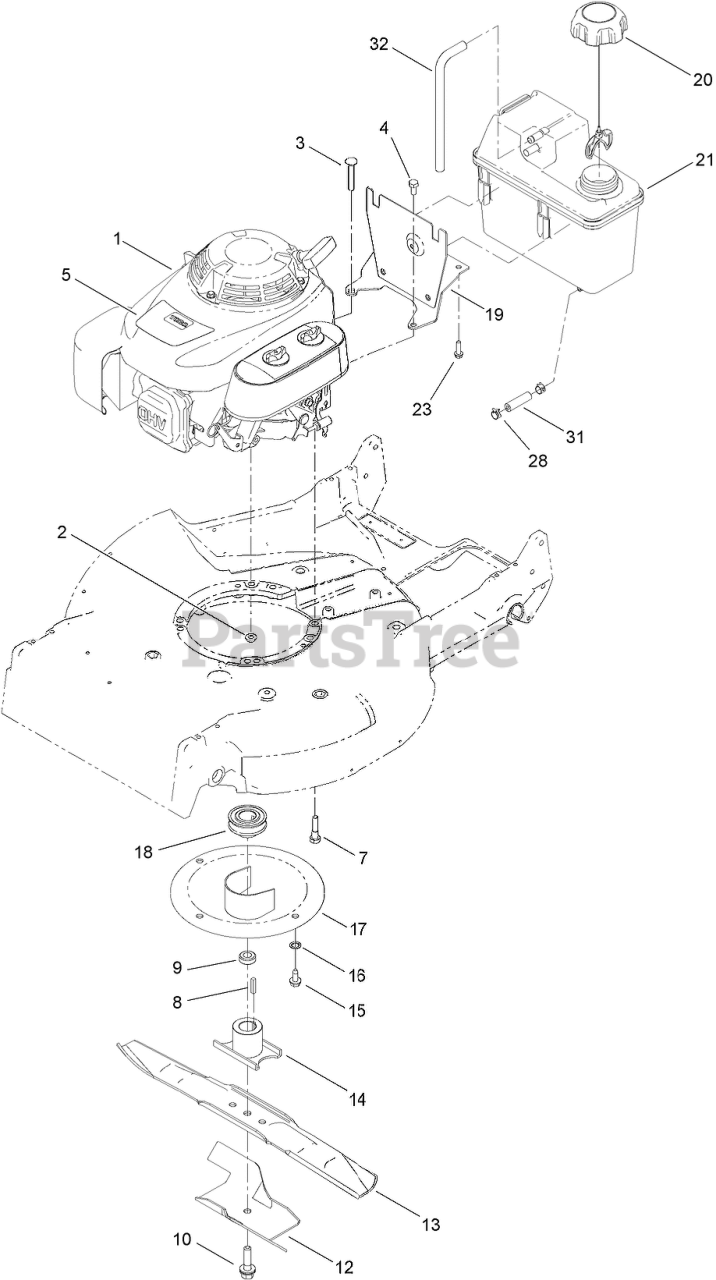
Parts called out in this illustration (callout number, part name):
2	NUT-HF
3	Screw-CARR
4	SCREW-HH
5	DECAL-ENGINE, HONDA
7	SCREW-SHOULDER
8	KEY-SQUARE
9	Spacer-Retainer, Blade
10	BOLT-BLADE
12	STIFFENER-BLADE
13	BLADE-21 INCH
14	RETAINER-BLADE
15	SCREW-HWHTF
16	WASHER-LOCK, INTERNAL
17	CRANKSHAFT PROTECTOR ASM
18	PULLEY-DRIVER
19	MOUNT-TANK
20	CAP-RATCHET, TETHERED
21	TANK-FUEL
23	SCREW-HWH
28	CLAMP-HOSE
31	HOSE-FUEL
32	HOSE-VENT, CANISTER
